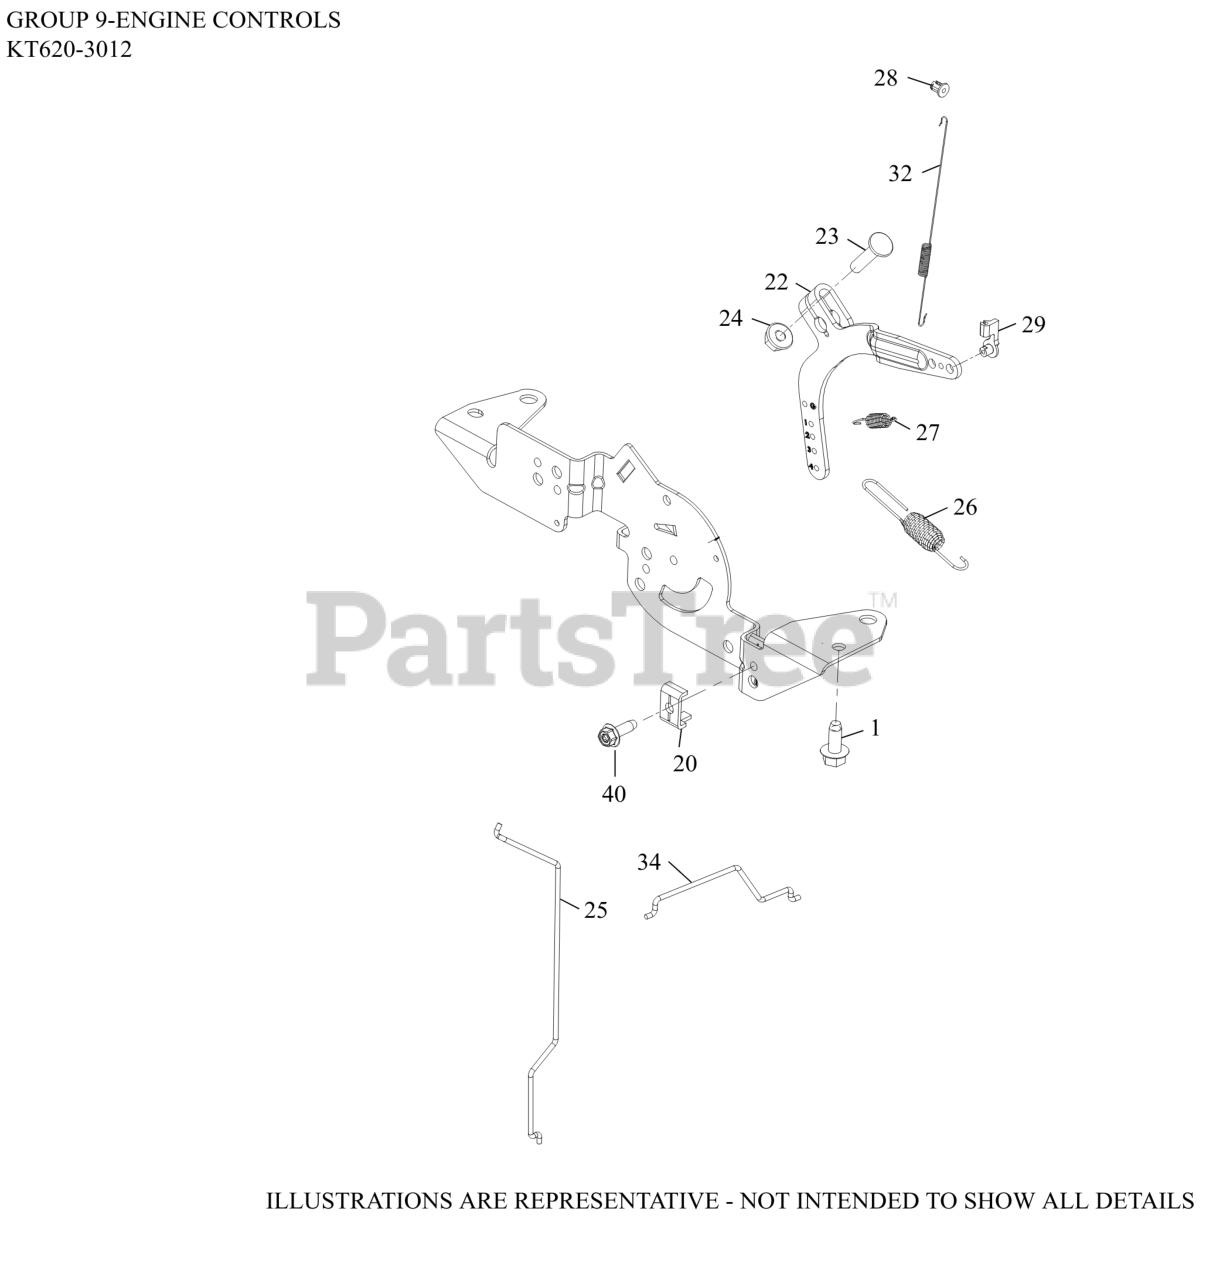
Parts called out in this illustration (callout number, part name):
1	SCREW, THREAD FORMING
20	CLAMP, CABLE-(#2523753S)
22	LEVER, GOVERNOR - (#2409069S)
23	BOLT, RD HD SQ NECK M6X1.0X25
24	NUT, FLANGE 1/4-20
24	NUT, FLG M6X1.0
25	LINKAGE, CHOKE
26	SPRING, GOVERNOR (ORANGE)
27	SPRING, GOVERNED IDLE
28	BUSHING, LINKAGE RETAINING
29	BUSHING, THROTTLE LINKAGE
32	SPRING, LINKAGE
34	LINKAGE, THROTTLE
40	SCREW, THREAD FORMING
